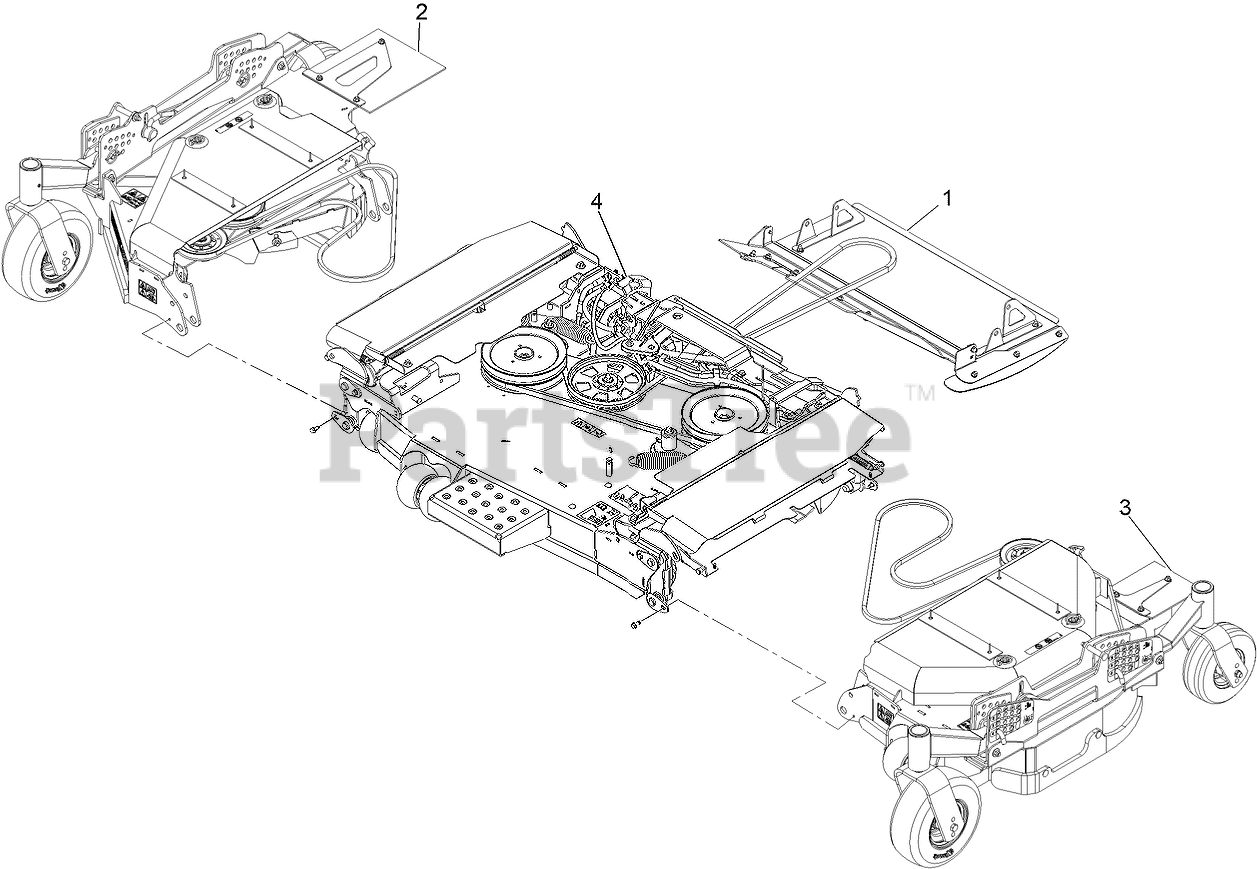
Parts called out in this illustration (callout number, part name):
1	Discharge-Tunnel ASM, 96-Gas
2	ASM-Deck, RH Wing 96
3	ASM-Deck, LH Wing 96
4	ASM-Deck, Ctr 96
